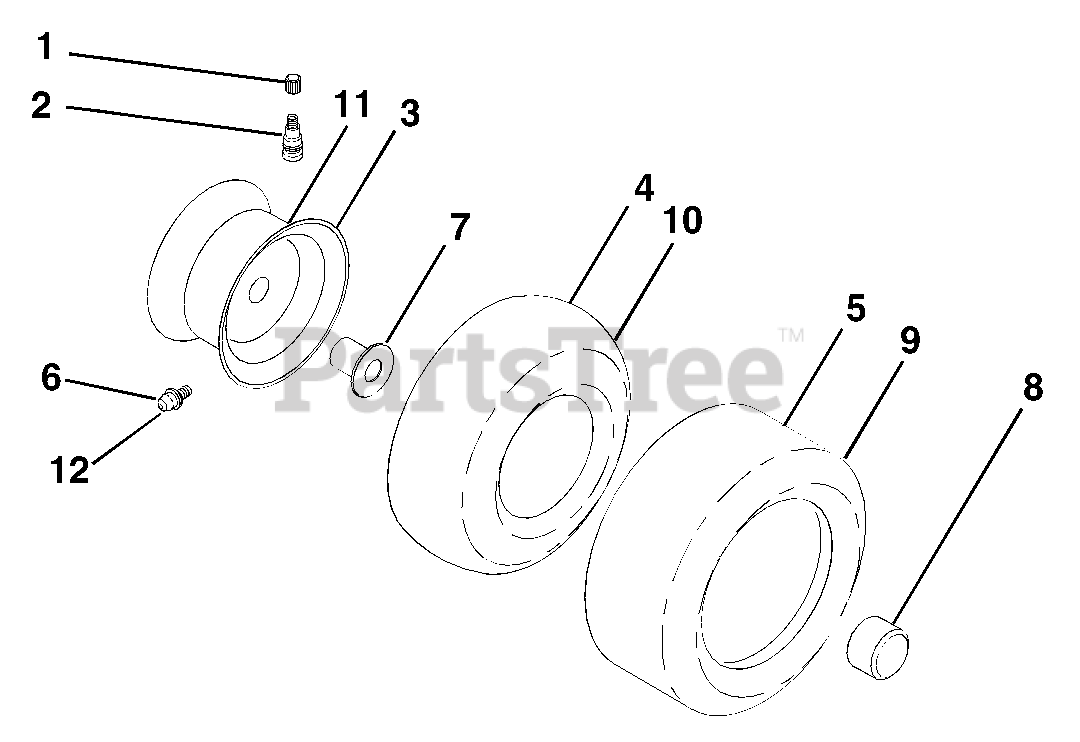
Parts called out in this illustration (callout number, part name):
1	Cap, Valve, Tire
2	Stem, Valve
3	Rim Assembly, Front
4	Tube, Front
5	Tire, Front
6	Fitting, Grease (Front Wheel Only)
7	Bearing, Flange (Front Wheel Only)
8	Cap, Axle (Front Wheel Only)
9	Tire, Rear
10	Tube, Rear
11	Rim Assembly, Rear
12	Fitting, Grease
